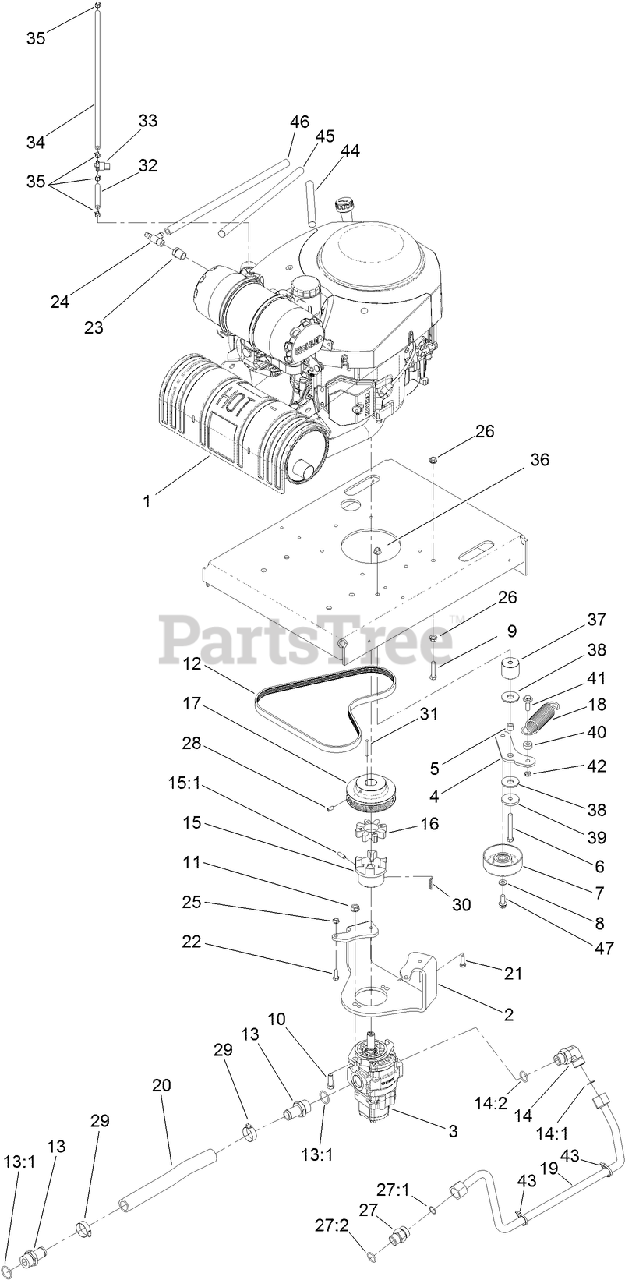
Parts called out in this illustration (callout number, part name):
2	MOUNT-PUMP
3	GEAR PUMP ASM
4	ARM-IDLER
5	BUSHING-LEVER, LIFT
6	SCREW-HH
7	PULLEY-IDLER
8	WASHER-FLAT
9	SCREW-HH
10	SCREW-HH
11	NUT-HF
12	BELT-V
13	FITTING-STR
13:1	O-RING
14	FITTING-ELBOW-90
14:1	O-RING
14:2	O-RING
15	HUB-COUPLER
15:1	SCREW-SET
16	SPIDER
17	PULLEY-ENGINE
18	SPRING-EXTENSION
19	TUBE-HYD
20	HOSE-SUCTION
21	SCREW-HH
22	SCREW-HH
23	BUSHING
24	Valve-Drain, Oil
25	NUT-HF
26	NUT-HHF, WHIZ
27	FITTING-STR
27:1	O-RING
27:2	O-RING
28	SCREW-SET, HSH
29	CLAMP-HOSE
30	KEY-SQUARE
31	KEY-SQUARE
32	HOSE-FUEL
33	VALVE-FUEL
34	HOSE-FUEL
35	CLAMP-HOSE
36	NUT-HF, NI
37	SPACER-IDLER
38	WASHER-FRICTION, COMPOSITE
39	WASHER-PLAIN
40	SPACER
41	SCREW-SHOULDER, HWH
42	NUT-LOCK, NI
43	TIE-CABLE
44	SLEEVE-THERMAL,
45	SLEEVE-THERMAL,
47	SCREW-HHF
